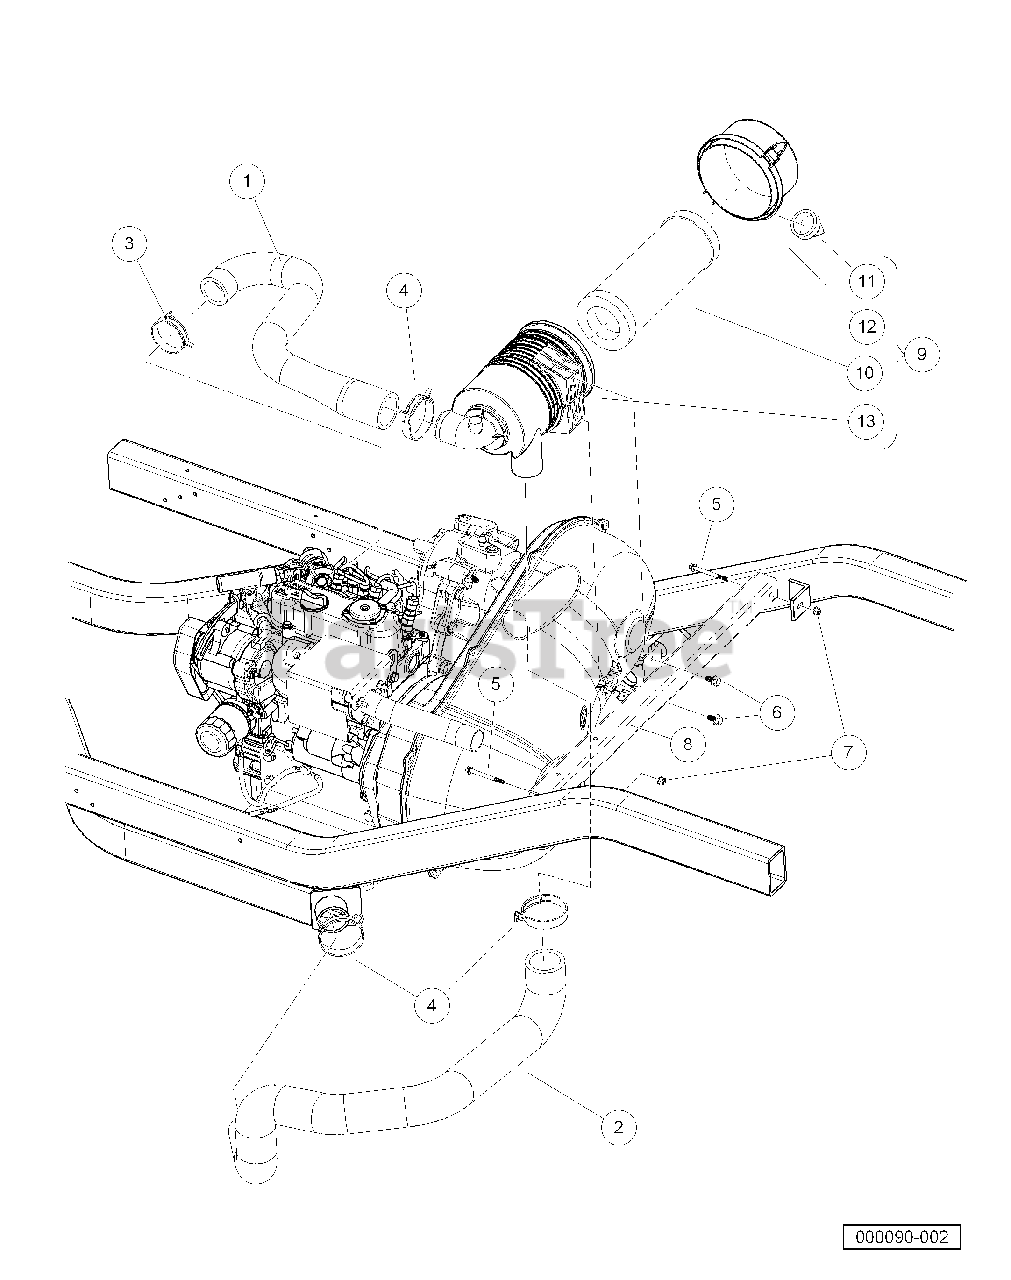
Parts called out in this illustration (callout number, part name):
1	Hose, Intake, D722
2	Hose, Intake, Primary
3	Clamp, Hose, Ctb 55mm
4	Clamp, Hose, Ctb 64mm
5	Bolt, M 6 X 1.0 X 65 Hex, Flange, Head, Black
6	Bolt Flanged Head, M8 X1.25x 16 with Loctite
7	Nut Flg, M6 X 1.0 Nylon
8	Weldment, Support, Air Cleaner
9	Filter, Air, Canister, W/labe
10	Element, Filter, Air, 5 In
11	Valve, Evacuator, Filter Air
12	Cap, Latch Lock, Filter, Air
13	Body, Canister, Filter, Air
